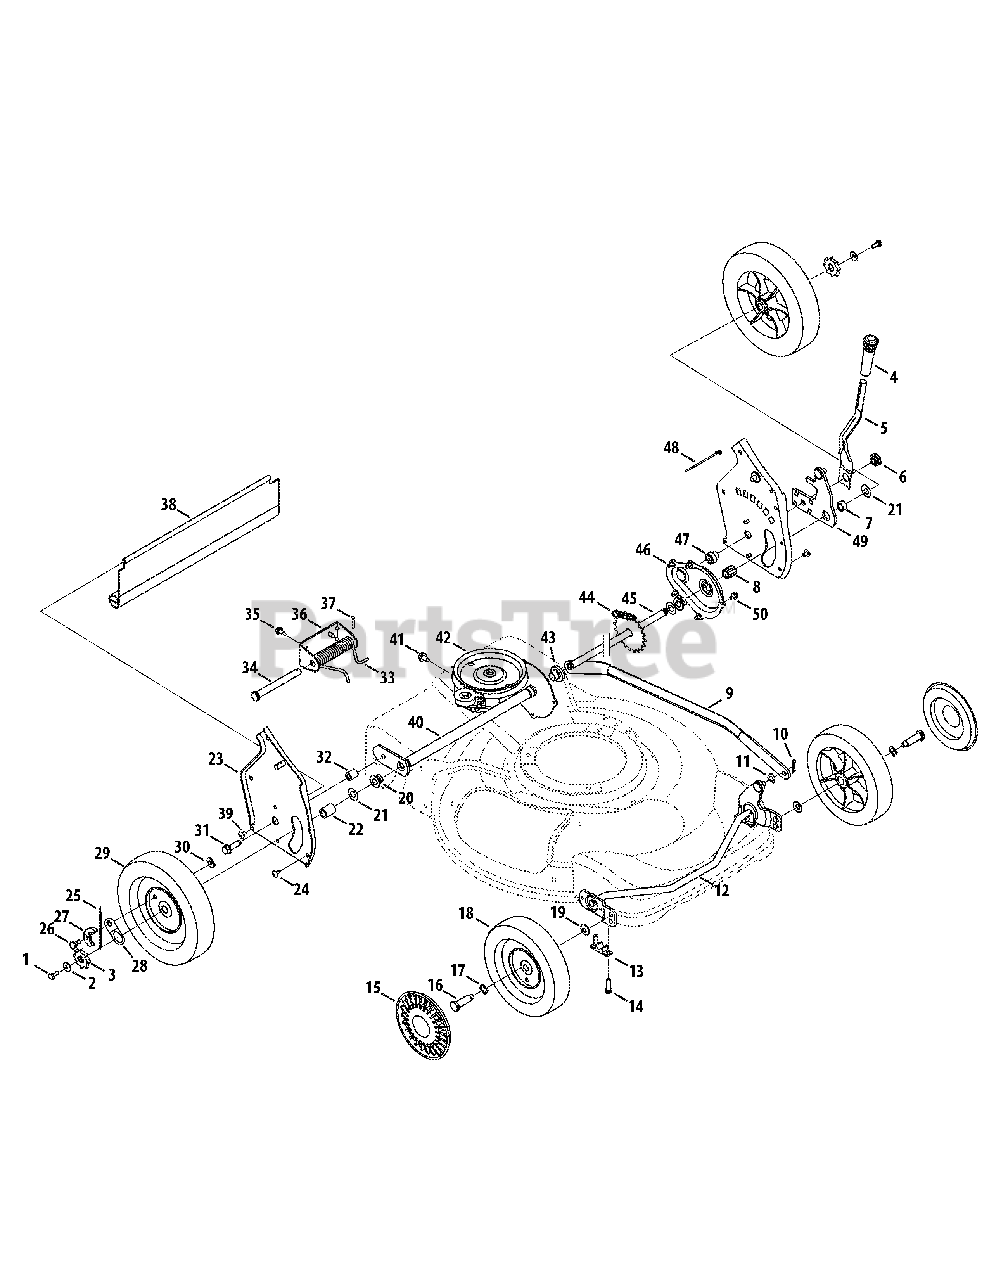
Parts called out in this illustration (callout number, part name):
1	HH Cap Screw 1/4-20 x .620
2	Bell Washer .265 x .75 x .062
3	Wheel Ratchet
5	Spring Lever
6	Shoulder Nut
7	Spacer .51 x .70 x .38
8	Hex Sleeve Bearing
9	Single Lever Control Arm
10	Hairpin Clip
11	Bowed Washer
12	Front Axle Assembly
13	Block Bushing
14	Hex Screw 1/4-15 x 1
15	Hubcap
16	Shoulder Scr., .498x1.445x3/8-16
17	Wave Washer .510 x .750 x .017
18	Front Wheel
19	Bell Washer .375 x .870 x .063
20	Hex Flange Bearing
21	Flat Washer .508 x 1 x .020
22	Spacer .550 x .755 x 1.1
23	Handle Bracket Assy RH
23	Handle Bracket Assy LH
24	AB Screw 1/4-14 x .50
25	Plastic Ratchet Spring
26	Shoulder Scr., .340x.285x1/4-20
27	Pawl - RH
27	Pawl - LH
28	Ratchet Pawl Plate
29	Rear Wheel
30	Weld Nut
31	TT Screw 3/8-16 x 1.25
32	Spacer .385 x .625 x .700
33	Torsion Spring RH
34	Clevis Pin .500 x 4.62
35	TT Screw 1/4-20 x .625
36	Lift Assist Spring Bracket
37	Cotter Pin
38	Trail shield
39	AB Screw, #10-16 x .500
40	Transmission Axle Assembly
41	TT Screw 5/16-18 x .625
42	Transmission
43	Hex Flange Bearing
44	Chain
45	Axle Assembly RR
46	Chain Cover Assembly
47	Shoulder Spacer .385 x .715
48	Cable Tie
49	RR Pivot Arm Assembly
50	TT Screw, 1/4-20 x .375
